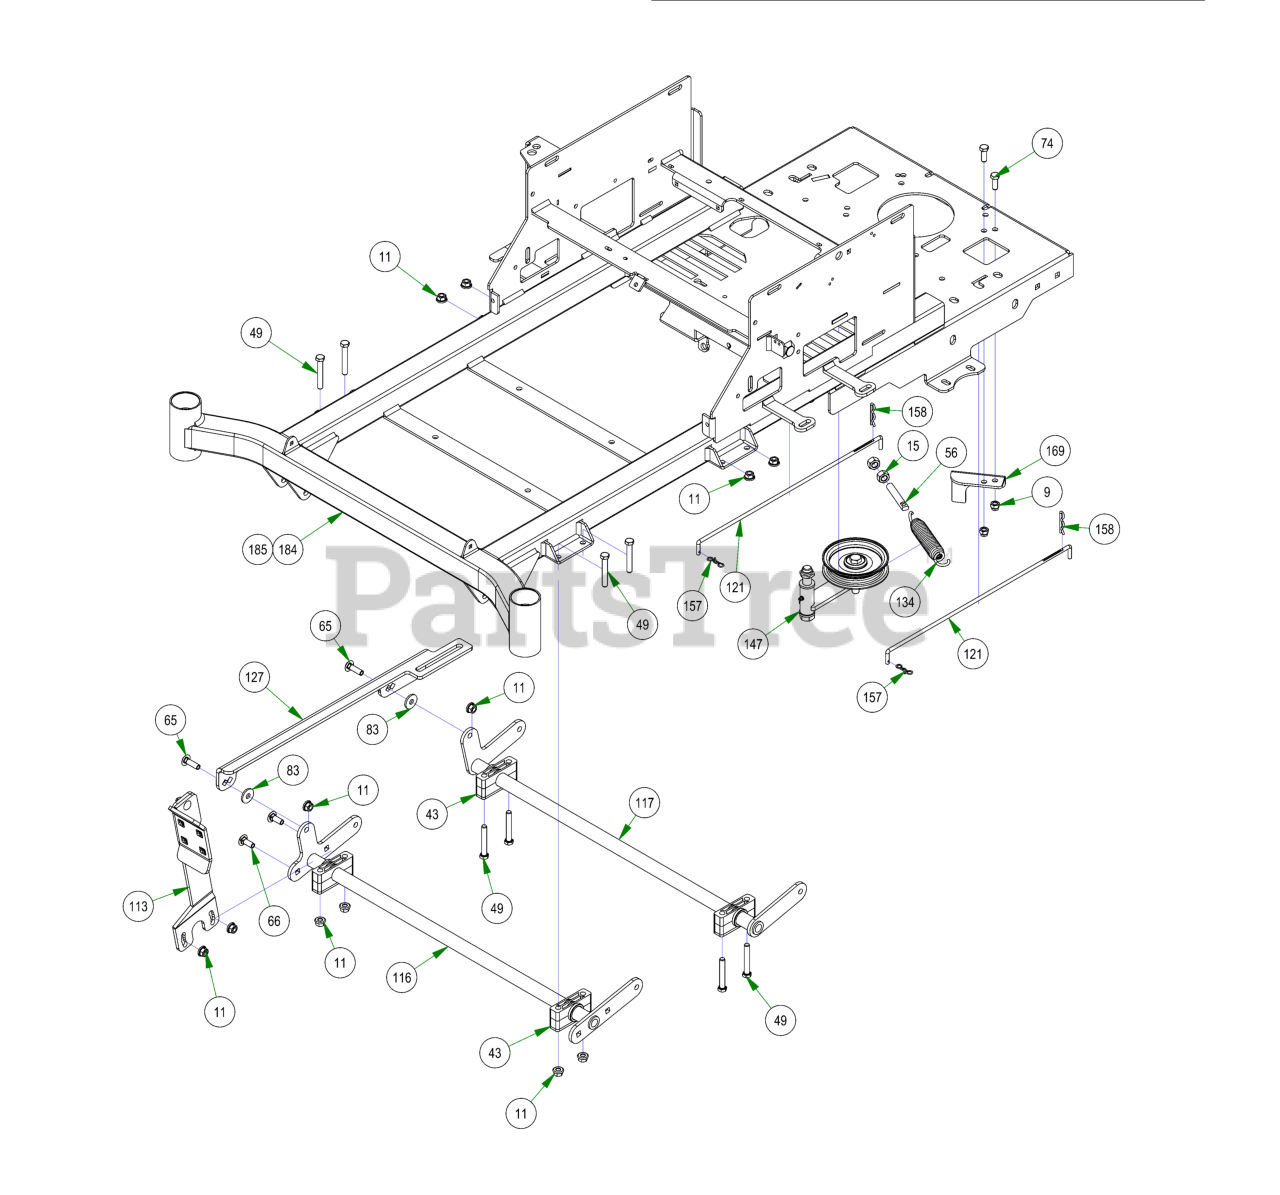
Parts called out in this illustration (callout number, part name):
9	3/8-16 NYLON INSERT LOCKNUT ZINC
11	3/8-16 NYLON INSERT FLANGE LOCKNUT (GR.F) ZINC
15	1/2-13 HEX NUT ZINC
43	Pillow Block Kit
49	3/8-16 X 2-1/2 HEX CAP SCREW (GR.5) ZINC
56	All Thread
65	3/8-16 X 1-1/4 CARRIAGE BOLT ZINC
66	3/8-16 X 1 CARRIAGE BOLT (GR.5) ZINC
74	3/8-16 X 1 GR 5 Hex Bolts Zinc
83	.390 ID X 1.12 OD X .125 THK FLAT WASHER NYLON
113	Foot Pedal Assembly
116	Actuator Bar Front- 2017 MZ/ZT
117	Actuator Bar Rear- 2017 MZ/ZT
121	Neutral Rod
127	2017 MZ/ZT Actuator Linkage
134	Deck Idler Spring
147	ZT Pump Idler
158	Neutral Rod Clip
169	2017 MZ Clutch Stop
184	2023 MZ 42-48 Frame - Painted
185	2023 MZ-Avenger 54-60 Frame - Painted
